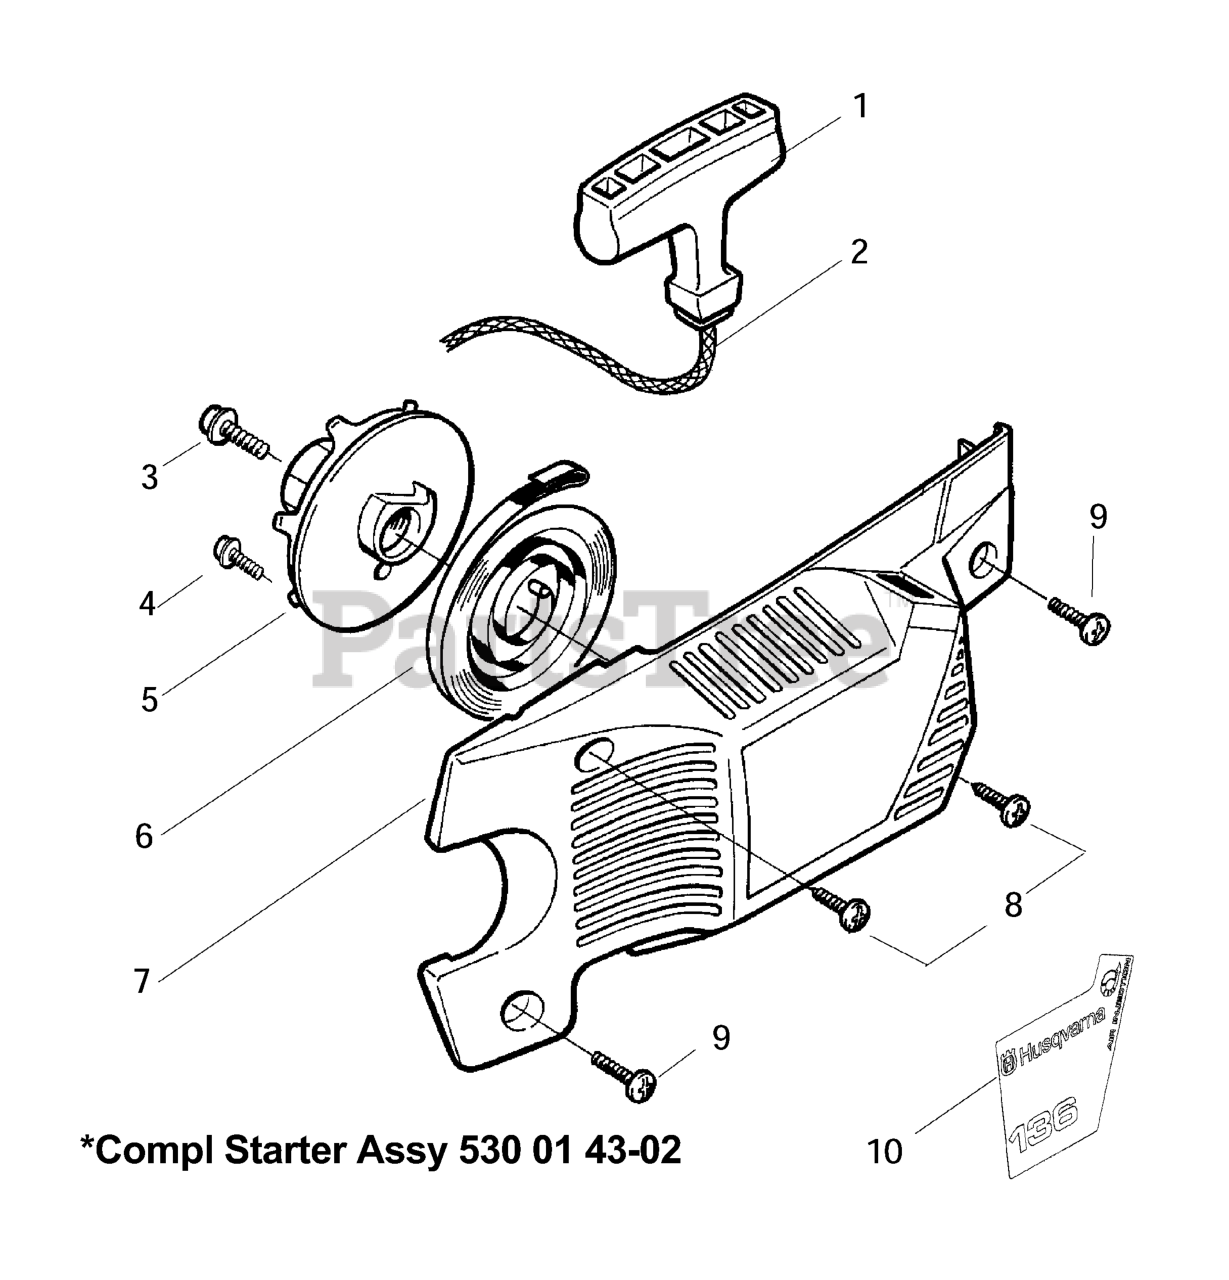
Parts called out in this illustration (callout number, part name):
1	STARTER HANDLE
5	PULLEY 36/41
6	RETURN SPRING
7	FAN HOUSING ASSEMBLY
8	SCREW,STRTR CVR 36/41
530014302	STARTER ASSEMBLY
